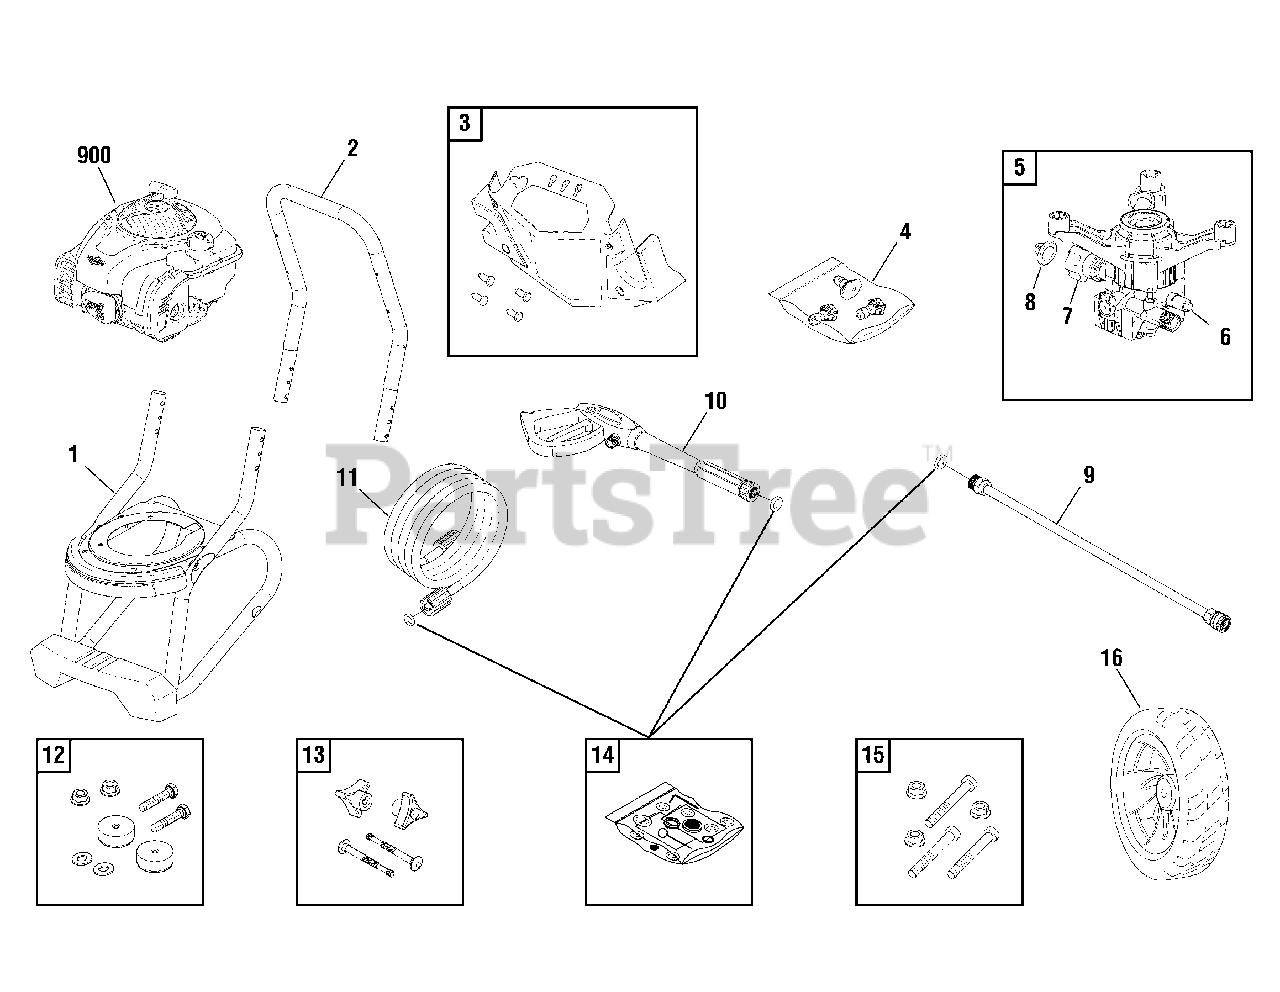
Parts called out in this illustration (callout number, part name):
4	KIT-QC NOZZLES
6	VALVE-THERMAL RELIEF
7	ADAPTER-GARDEN HOSE
9	EXTENSION-QC
10	GUN
11	HOSE
12	MOUNT-VIBRATION
13	KIT-HARDWARE HANDLE
15	KIT-HARDWARE PUMP MOUNTING
900	** ENGINE
